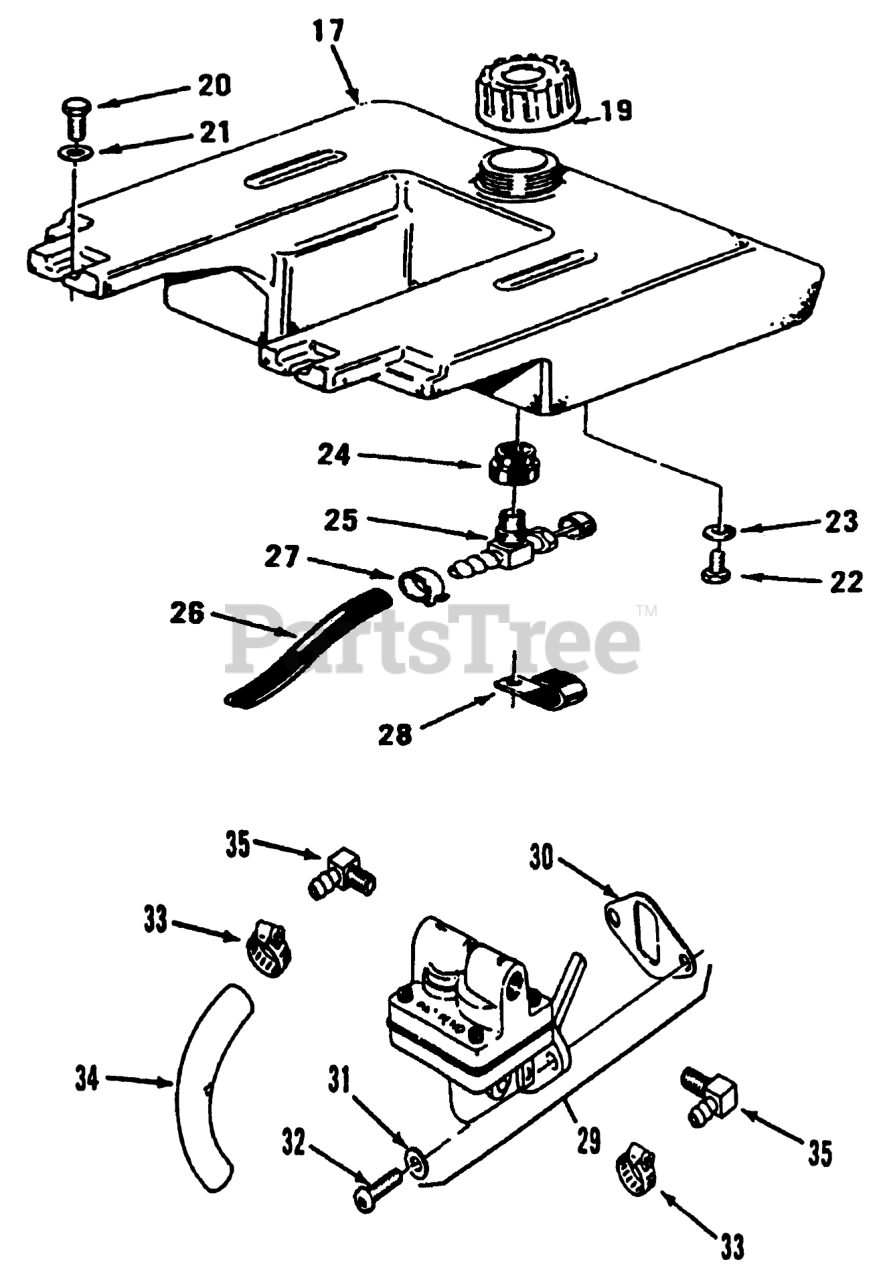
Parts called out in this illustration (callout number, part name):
17	TANK-FUEL
19	GAS CAP ASM
20	Bolt
21	WASHER-FLAT
22	SCREW-HH
23	WASHER-LOCK
24	BUSHING
25	VALVE-FUEL
26	Fuel Line 62
27	Clamp
28	Clamp
29	Pump Assy-Fuel (Includes Items 30 & 31)
30	Gasket
31	Washer
32	Screw-Pozidrive
33	Clamp
34	Line-Fuel
35	Connector 90
